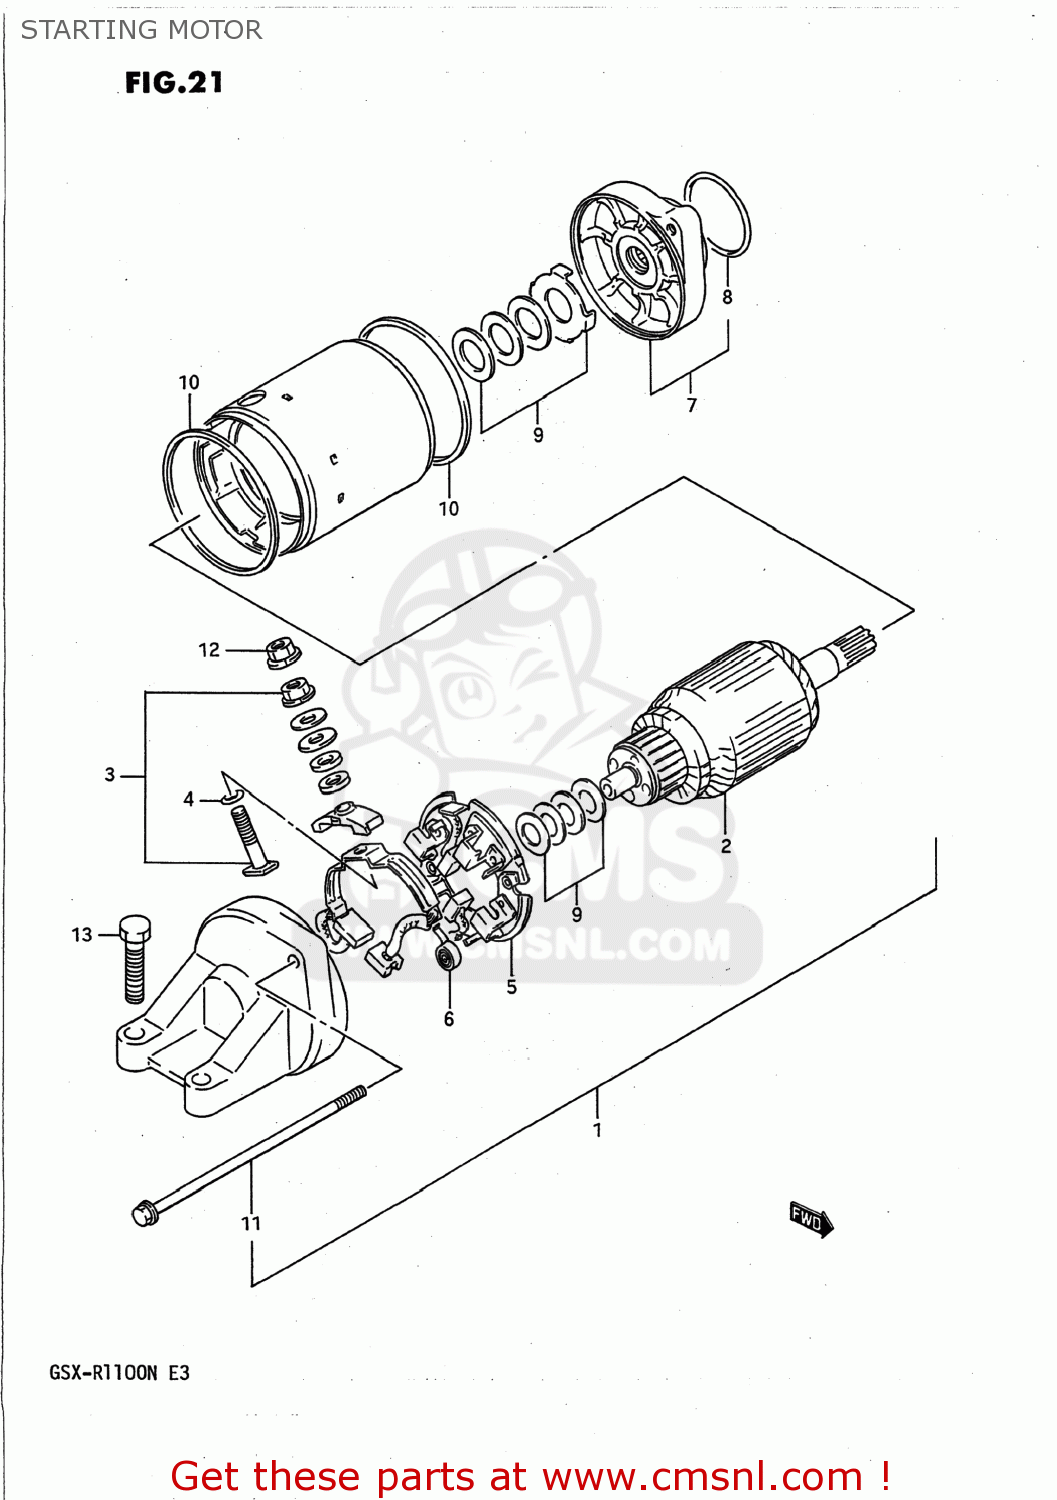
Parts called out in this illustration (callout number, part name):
1	MOTOR ASSEMBLY,STARTING
2	ARMATURE
3	TERMINAL SET,BRUSH
4	O RING
5	HOLDER SET,BRUSH
6	SPRING,BRUSH
7	BRACKET
8	O-RING
9	SHIM SET,STARTING MOTOR
10	O RING
11	BOLT
12	NUT
13	SCREW (6X25)
